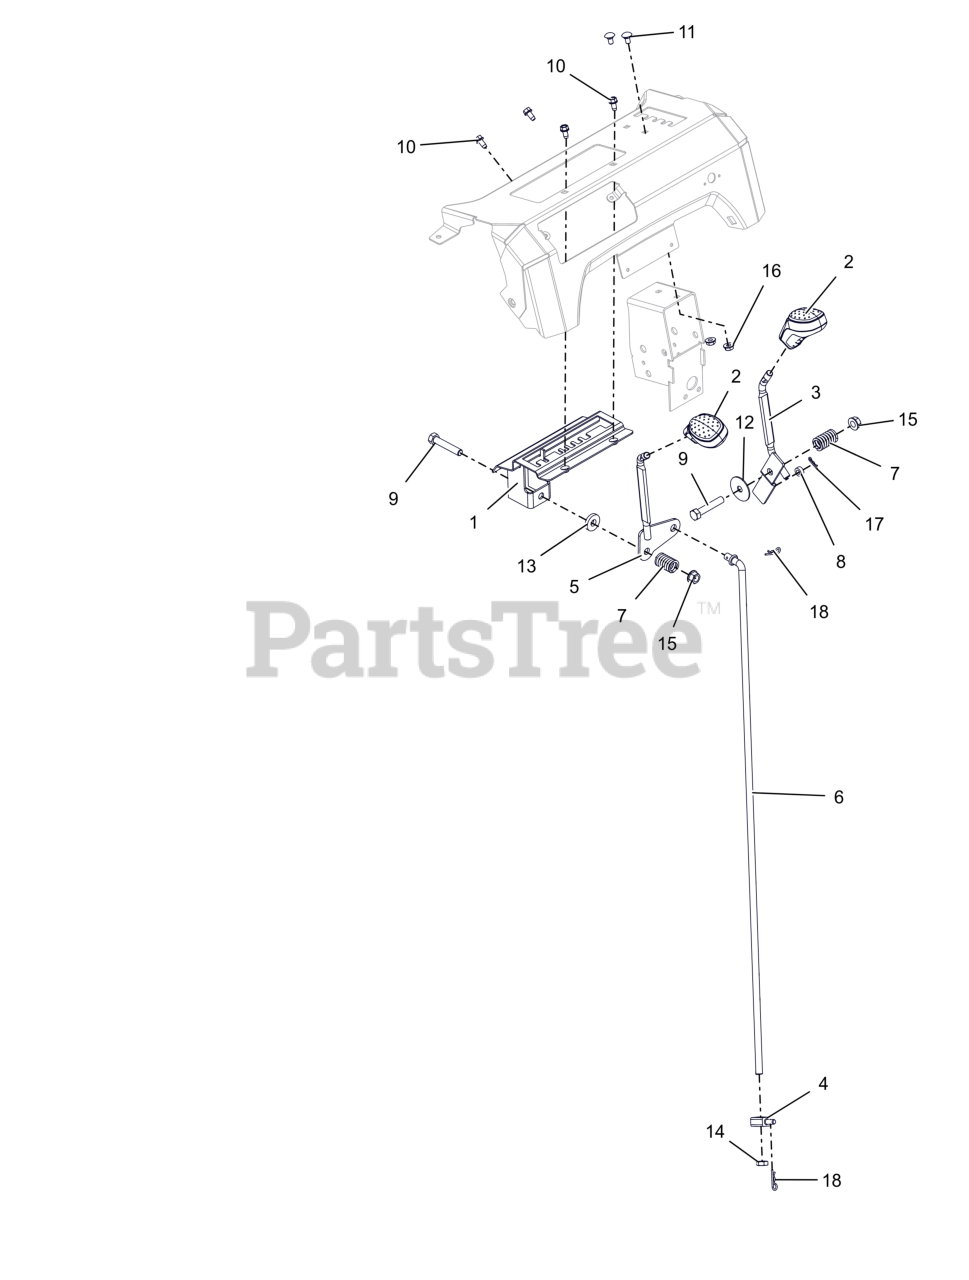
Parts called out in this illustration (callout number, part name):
1	WELDMENT, DETENT PLATE-COMPACT
2	KNOB, CONTROL, DASH
3	WELDMENT,SM DASH DEFL CONTROL
4	PIVOT,SHIFT ROD .375-16(TRUNN)
5	LEVER, CONTROL-SHIFT(WELDMENT)
6	ROD, SHIFT - SMALL DASH DELUXE
7	SG-COMP .125X.781X1.250
8	BSHG-SLV .265X.500X.219
9	BLT,HEX .38-16X2.00 G5 ZCC
10	SCR-TAP .25-20X.50 HWH ZCC
11	BLT, RHSN .25-20X.500 G5 ZCC
12	WSHR,FLT .380X1.50X.062 ZCC
13	WSHR, FLT .406X1.00X.188 ZCC
14	NUT-JAM .375-16 G2 ZCC
15	NUT-LK-TOP-FLG .38-16 ZC120
16	NUT-LK-TOP-FLG .250-20 GF ZCC
17	PIN, HAIR #178 .06X.77 ZCC
18	PIN, HAIR #213 .08X1.19 ZCC
